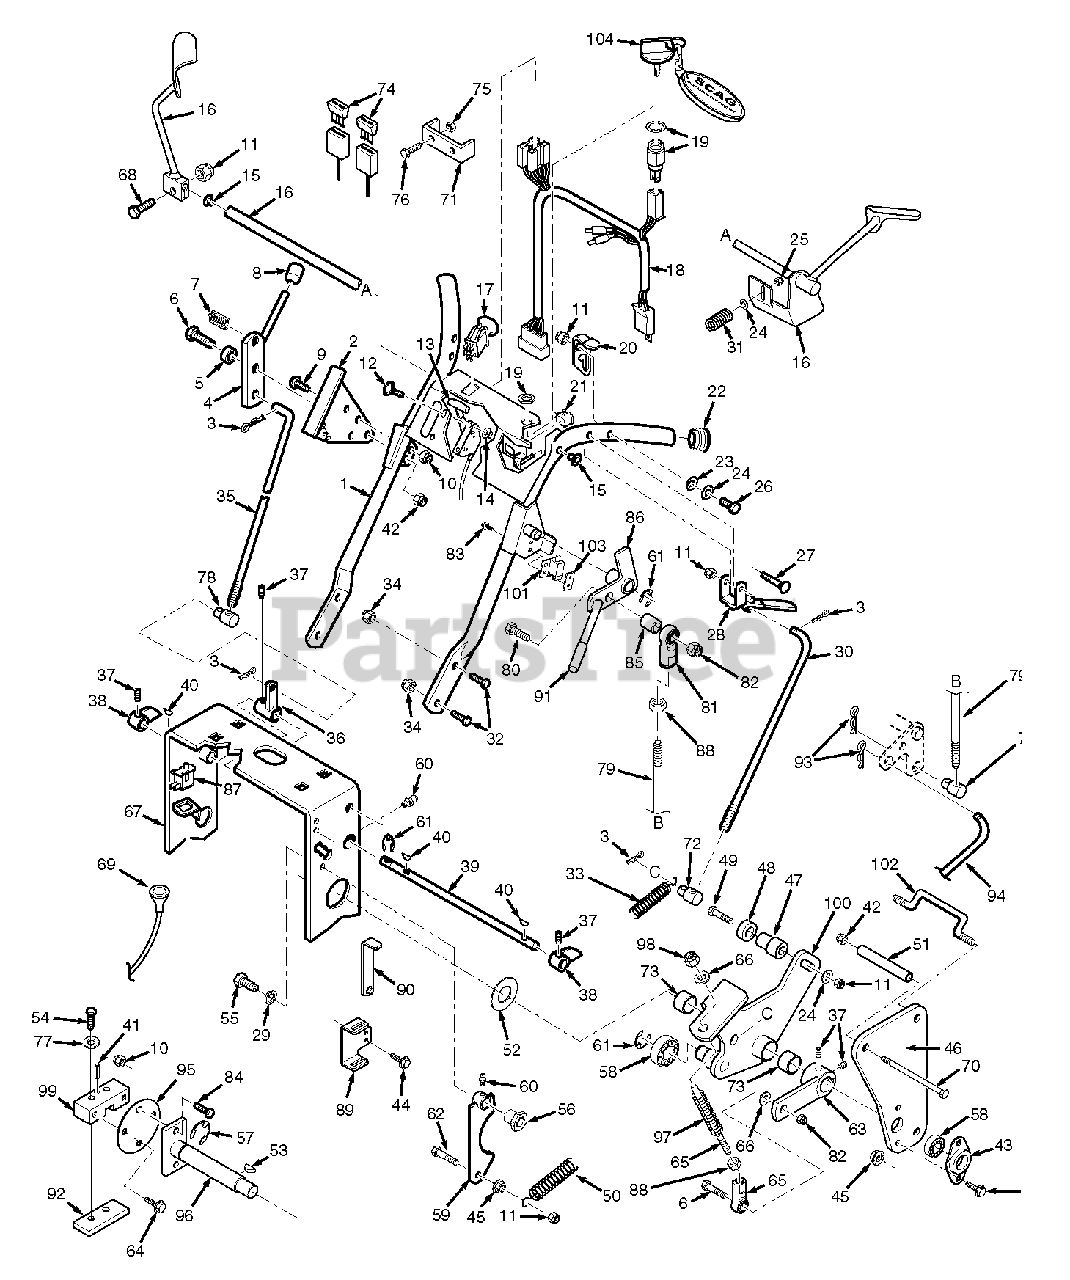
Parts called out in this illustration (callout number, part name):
1	Upper Handle Wlmt. W/Decals
2	Quadrant, Speed Control
3	Hairpin, .094 x 1.19
4	Lever, Speed Adjustment
5	Bushing, Speed Adjustment Lever
6	Hex Head Bolt, 3/8-16 x 1.5"
7	Ball Plunger
8	Knob, Speed Adjustment
9	Capscrew, 1/4-20 x 3/4" FHHS
10	Nut, 1/4-20 Elastic Stop
11	Nut, 5/16-18 Elastic Stop
12	Screw, #10-32 x 1/2" PW HD
13	Throttle Control
14	Nut, #10-32 Serr. Flange
15	Bushing
16	Handle, Oper. Presence-RH
16	Handle, Oper. Presence-LH
17	Switch, Electric Clutch Engage
18	Wire Harness, Manual Start
18	Wire Harness, Electric Start
19	Key Switch, Manual Srt. (inc. Hdw)
19	Key Switch, Electric Srt. (inc. Hdw)
20	Neutral Latch-RH
20	Neutral Latch-LH
21	Switch, Neutral Interlock
22	Plug, Handlebar
23	Washer, Curved Spring
24	Flat Washer
25	Nut, 5/16-18 Elastic Stop
26	Hex Head Bolt, 5/16-18 x 2"
27	Hex Hd. Bolt, 5/16-18 x 2.5"
28	Lever, Steering Control
29	Lockwasher, 3/8 Spring
30	Rod, Steering Control
31	Spring, Operator Presence
32	Capscr., 3/8-16 x 1" Ser. Flange
33	Spring
34	Nut, 3/8-16 Serr. Flange
35	Rod Speed Control
36	Bellcrank, Speed Control
37	Setscrew, 1/4-28 x .25"
38	Cam, Speed Control
39	Jackshaft, Speed Control
40	Key, 1/8 x 1/2" Woodruff
41	Roll Pin, 3/16-.75
42	Nut, Elastic Stop 3/8-16
43	Flange, Bearing
44	Capscrew, 5/16-18 x 1" Serr. Flg.
45	Nut, 5/16-18 Serrated Flange
46	Plate, Side
47	Spacer, Neutral Bearing
48	Bearing, Speed Ctrl. Bellcrank
49	Hex Head Bolt, 5/16-18 x 1-3/4"
50	Spring, Return
51	Spacer, Side Plate
52	Flatwasher, .766 x 1.25 x .035
53	Key, Woodruff, 3/16 x .75
54	Bolt, Hex Head, 1/4-20 x 1.25"
55	Bolt, Hex Head, 3/8-16 x 1"
56	Bushing, Brake
57	Clip, Retaining .750 diameter
58	Bearing, Ball Neutral Return
59	Cam, Neutral (incl. grease ftng.)
60	Grease Fitting, 1/4-28 UNF
61	Retaining Ring, 5/8"
62	Hex Head Bolt, 5/16-18 x 1"
63	Lever, Speed Control
64	Bolt, Hex Head 1/4-20 x.75"
65	Linkage Assembly
66	Flat Wshr., 15/16 x .3906 x 12 ga
67	Deck, Engine 20" Wide
68	Hex Head Bolt, 5/16-18 x 1.25"
69	Choke Control
70	Bolt, Hex Head 3/8-16 x 4.25"
71	Fuse Holder - 21KAE
72	Swivel Joint, Steering Rod
73	Bushing
74	Blade Fuse, 20A - 21KAE
75	Nut, #10-32 Elastic Stop - 21KAE
76	Screw, #10-32 x 1.5" Phillips - 21KAE
77	Lockwasher, 1/4"
78	Swivel Joint
79	Rod, Brake Lever
80	Hex Hd. Bolt, 3/8-16 x 2"
81	Ball Joint, RH Thread
82	Nut, 3/8-16 Elastic Stop
83	Screw #10-32 Sltd Hex Wshr Hd
84	Bolt, 1/4-20 x .75"
85	Spacer
86	Parking Brake Lever with Grip
87	Switch, Safety
88	Nut, 3/8-24
89	Mounting Bracket, Wrench
90	Wrench
91	Grip, Parking Brake
92	Plate, Threaded
93	Hairpin, .094 x 1.62"
94	Rod, Lower Brake
95	Plate, Coupler
96	Shaft, Pump Control
97	Spring
98	Nut, 3/8-16 Elastic Stop
99	Block, Pump Control
100	Control, LH (inc. bush. & decal)
100	Control, RH (inc. bush. & decal)
101	Switch, Parking Brake
102	Rod, Offset
103	Plate, Threaded
104	Key Chain with Keys
104	Key with Shroud
